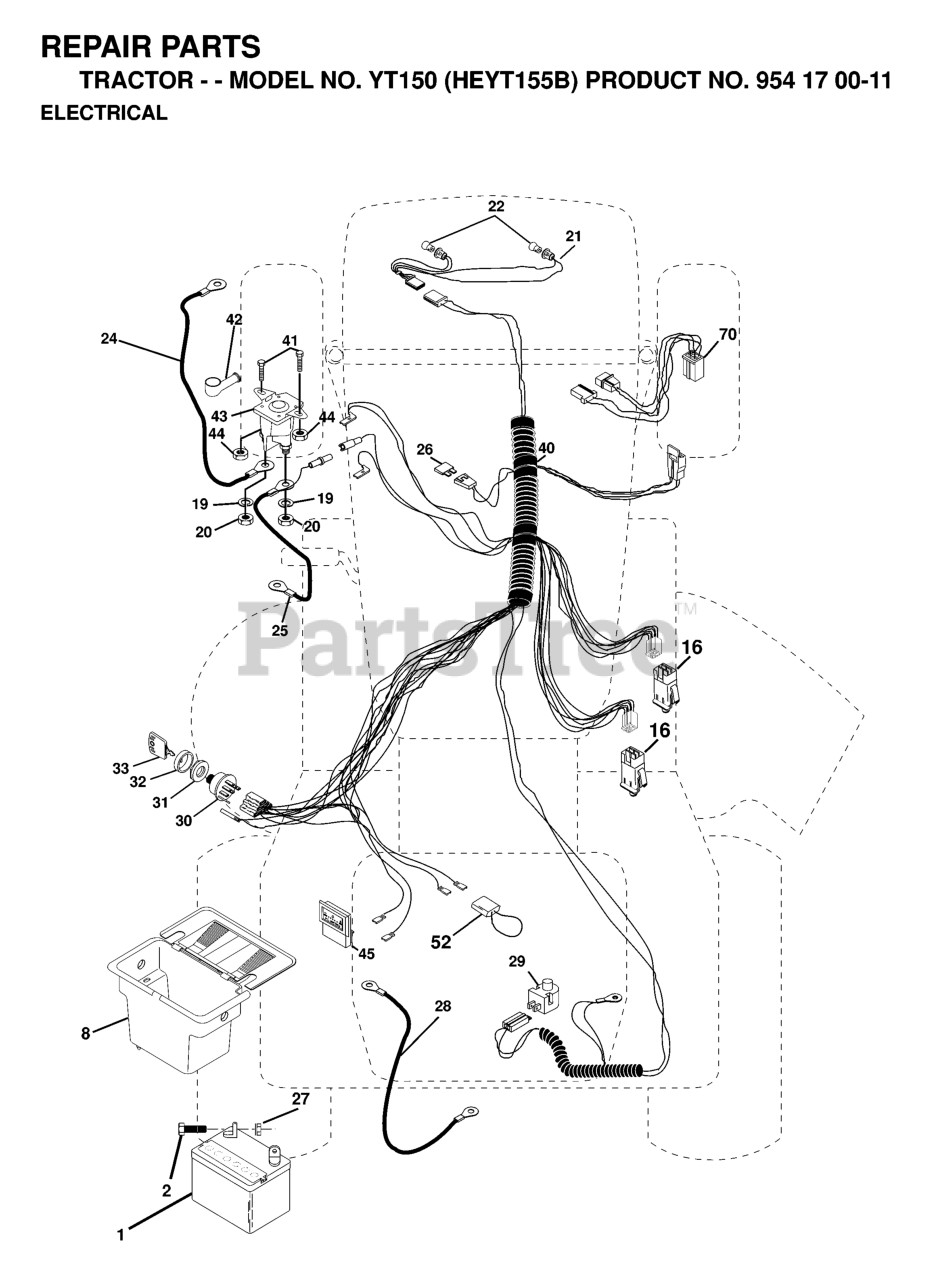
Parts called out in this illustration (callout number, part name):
1	BATTERY 12 VOLT 25 AMP
2	BOLT.HEX.1/4.X.3/4.DICHROMATE
8	CASE BATTERY MECH HINGE
16	SWITCH INTERLOCK
19	LOCKWASHER
20	NUT
21	HARNESS LIGHT SOCKET
24	BATTERY CABLE GT
25	CABLE BATTERY
27	NUT
28	CABLE T
29	RP.SWITCH.PLUNGER.NC.GRAY
30	SWITCH.IGNITION.4.POSITION
31	NUT IGNITION
32	COVER SWITCH KEY
33	KEY.MOLDED.GENERIC
40	HARNESS IGN
41	BOLT
42	TERMINAL COVER
43	SOLINOID
44	Nut, Keps Blk Hex 1/4-20 UNC
45	AMMETER
52	WIRE PROTECTION LOOP
70	HARNESS ENGINE
